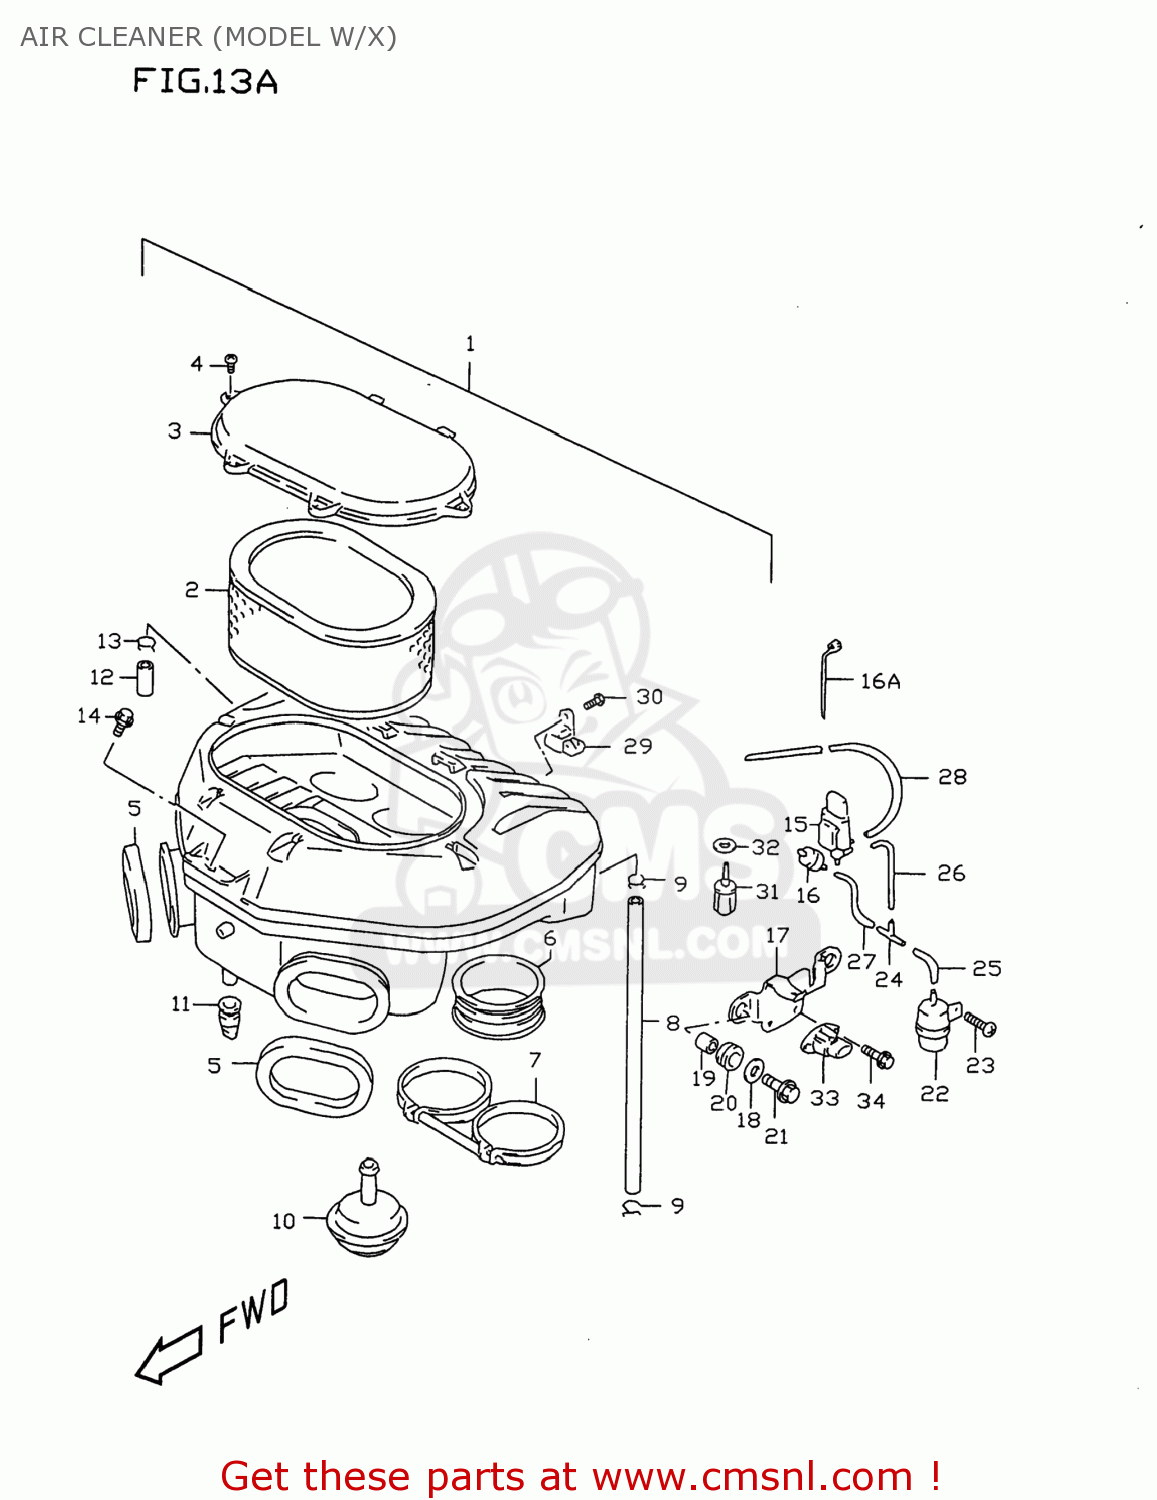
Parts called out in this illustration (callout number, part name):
1	CLEANER ASSEMBLY,AIR
2	FILTER,AIR CLEANER
3	CAP,AIR CLEANER
4	SCREW 5X12
5	CUSHION,DUCT
6	TUBE,OUTLET
7	CLAMP
8	TUBE,BREATHER
9	CLIP
10	DIAPHRAGM,CONTROL VALVE
11	CAP,DRAIN
12	PLUG
13	CLIP
14	BOLT
15	VALVE ASSY,3WAY SOLENOID
16	VALVE,CHECK
16A	CLAMP(L:125)
17	BRACKET,SOLENOID VALVE
18	WASHER(6.5X20X1.2)
19	SPACER(6.5X9X6.5)
20	CUSHION
21	BOLT
22	CHAMBER,VACUUM
23	SCREW 5X12
24	3 WAY
25	HOSE(4X8X600)
26	HOSE(4X8X600)
27	HOSE(4X8X600)
28	HOSE(4X8X600)
29	SENSOR,BOOST
30	SCREW 6X10
31	SENSOR,WATER TEMP
32	GASKET(12.2X21X0.8) (NAS)
33	SENSOR,MAP
34	BOLT
